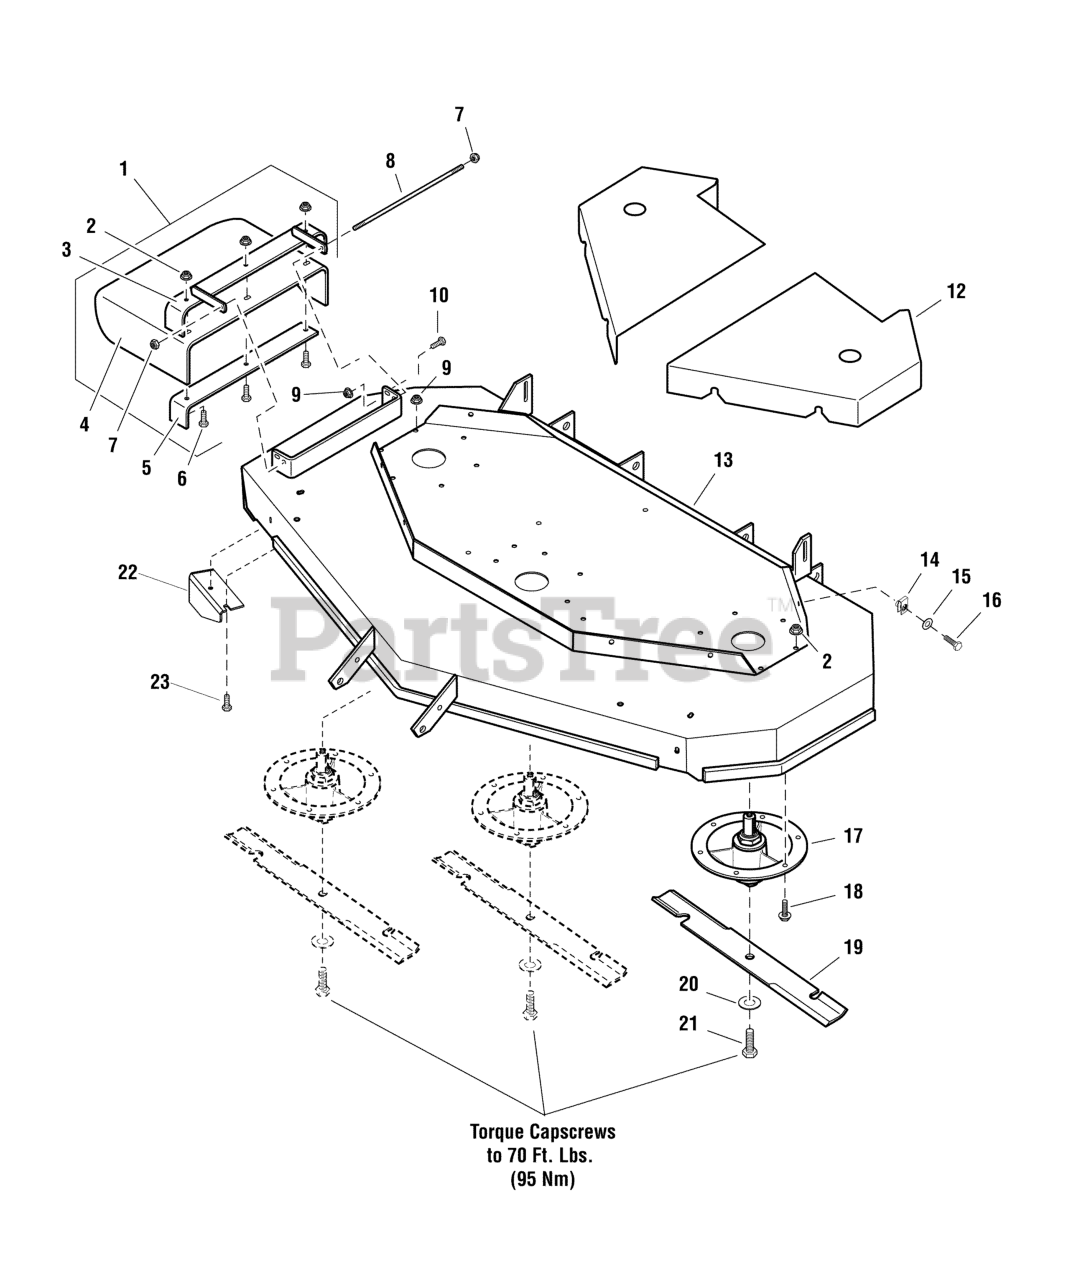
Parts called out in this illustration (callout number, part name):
1	PURCHASE INDIVIDUAL REPLACEMENT PARTS
2	NUT, 3/8-16 HEX NYLOCK FLANGE
3	WELD, FRAME, CHUTE, 61 - RED
4	CHUTE, DISCHARGE, RUBBER, 61/72, BENT
5	SUPPORT, DISCHARGE CHUTE - BLK
6	BOLT, 3/8-16 X 1-1/4" GD5 CZ
7	NUT, 5/16-24 HEX NYLON LOCK
8	ROD MOUNT, CHUTE 61"
9	NUT, 5/16-18 HEX NYLOCK FLANGE
10	BOLT, 5/16-18 X 3/4 GD5
11	GUARD, 61" RH - RED
12	GUARD, 61" LH - RED
13	DECK SHELL W/DECALS, 61" - IS5100
14	BODY CLIP, 5/16-18-7GA MATERIAL
15	WASHER, 5/16" SAE
16	BOLT, 5/16-18 X 3/4 GD5
17	SPINDLE ASSEMBLY
18	BOLT, 3/8-16 X 1-1/4", FLANGE
19	BLADE, 21
20	WASHER, 5/8" GRADE 8, YZ
21	BOLT, 5/8-11 X 1-3/4 GD8
22	PLATE, DEFLECTOR - BLK
23	BOLT, 5/16-18 X 3/4, CARRIAGE
